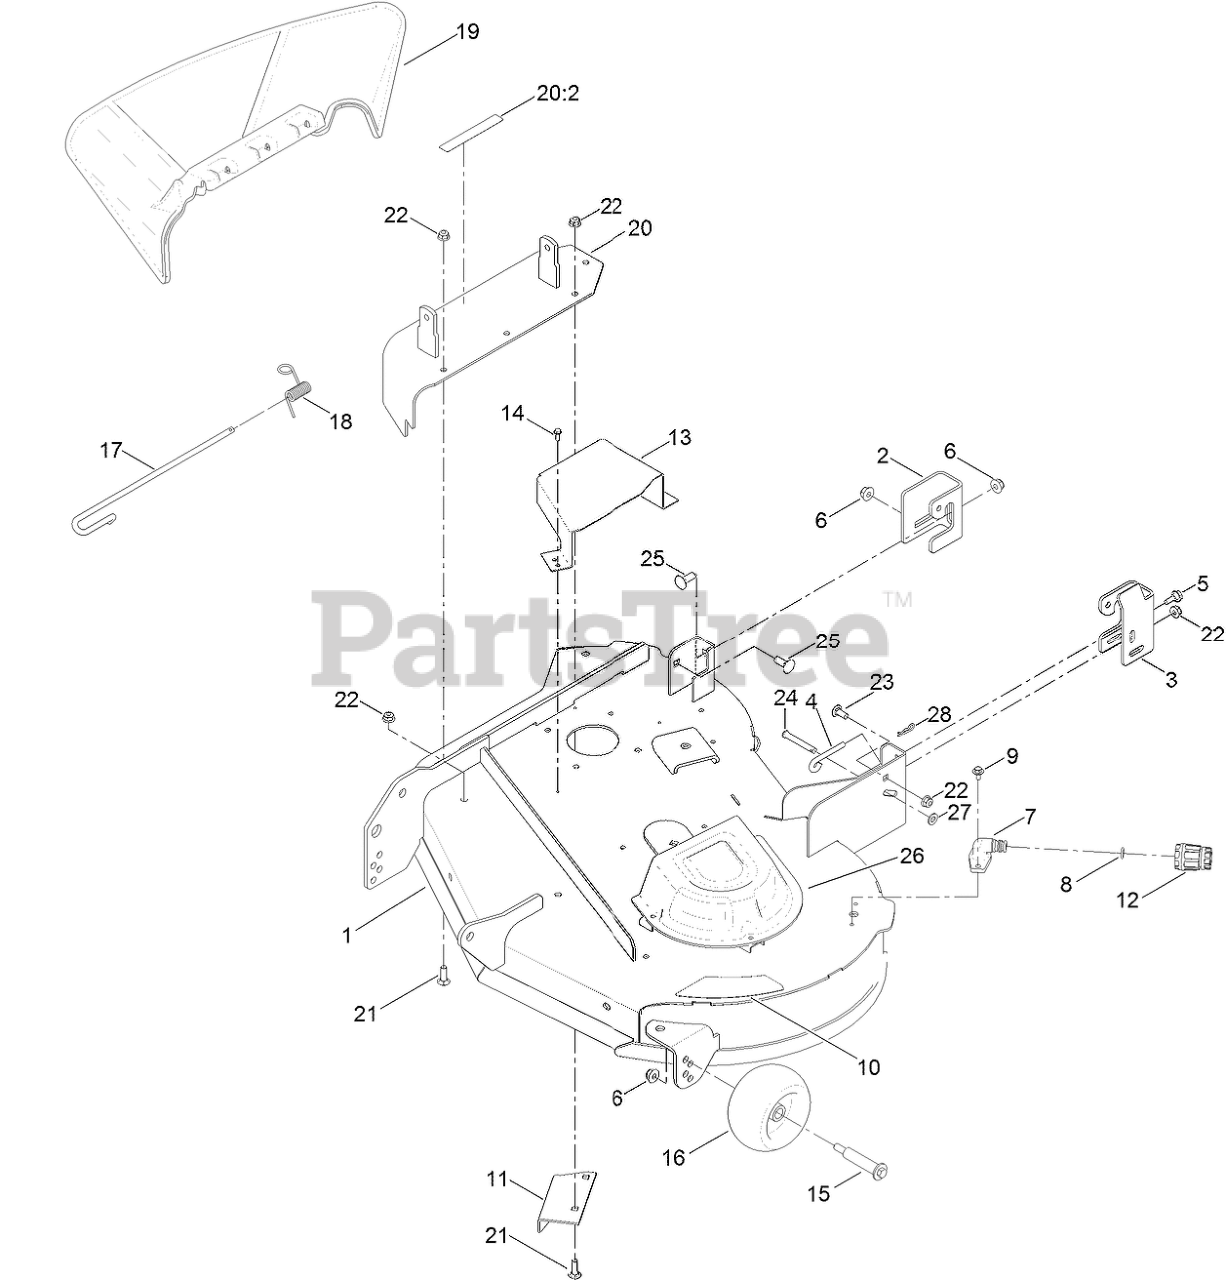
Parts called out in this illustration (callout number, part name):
1	34 INCH DECK ASM
2	BRACKET-HANGER, RH
3	BRACKET-HANGER, LH
4	ROD-LEVEL, DECK
5	SCREW-SHOULDER, HHF
6	NUT-HF, NI
7	FITTING-WASHOUT
8	O-RING
9	SCREW-HHFTF
10	DECAL-DECK
11	BAFFLE-CUTOFF
12	CONNECTOR-HOSE
13	COVER-DECK BELT
14	SCREW-TAPTITE
15	BOLT-SHOULDER
16	ROLLER-SCALP, ANTI
17	PIN-CHUTE
18	SPRING-TORSION
19	DEFLECTOR-DISCHARGE
20	COVER ASM W/DECAL
20:2	DECAL-DANGER
21	SCREW-CARR
22	NUT-HF, NI
23	SCREW-CARR
24	PIN-CLEVIS
25	BOLT-CARR
26	COVER-BELT
27	WASHER-PLAIN
28	PIN-COTTER
